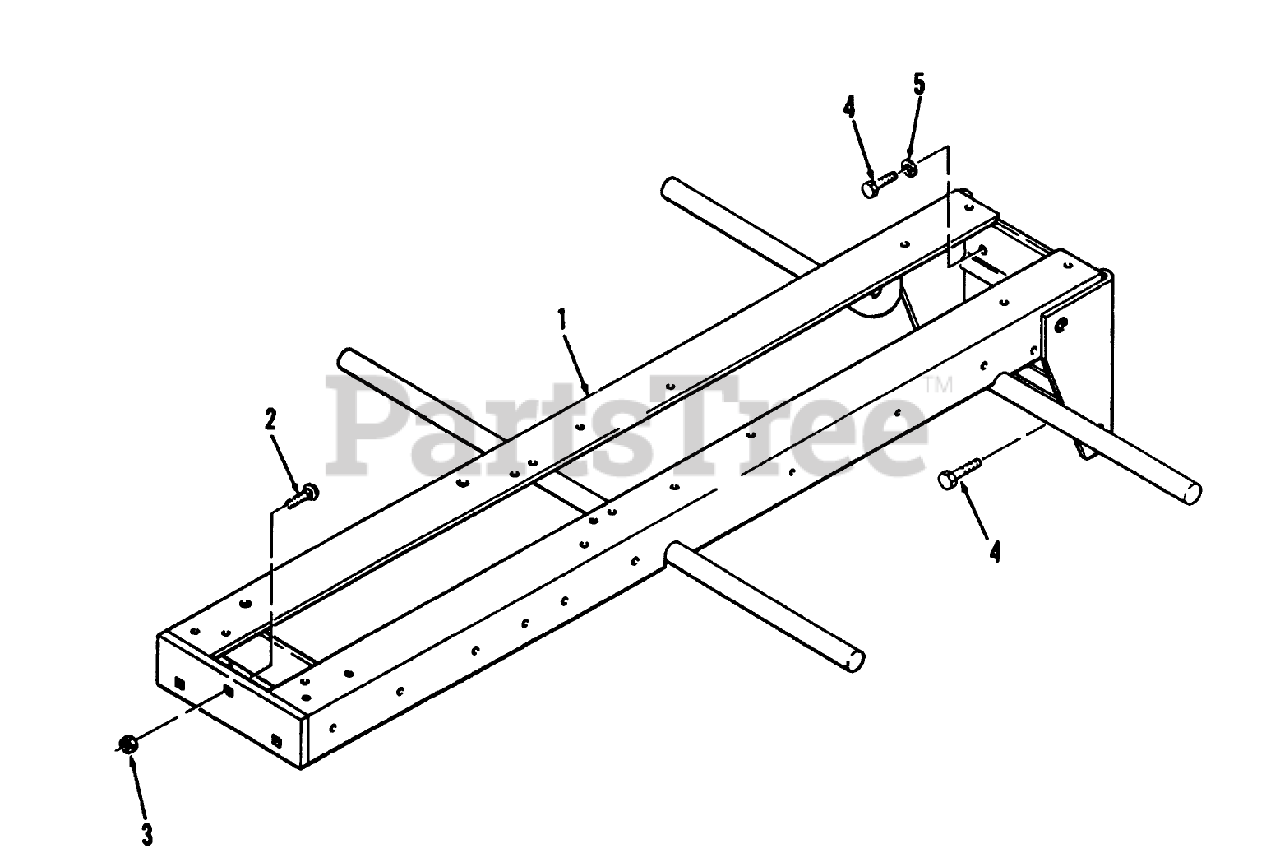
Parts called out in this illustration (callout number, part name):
2	BOLT-CARR
3	NUT-LOCK, NI
4	SCREW-HH
5	WASHER-LOCK
